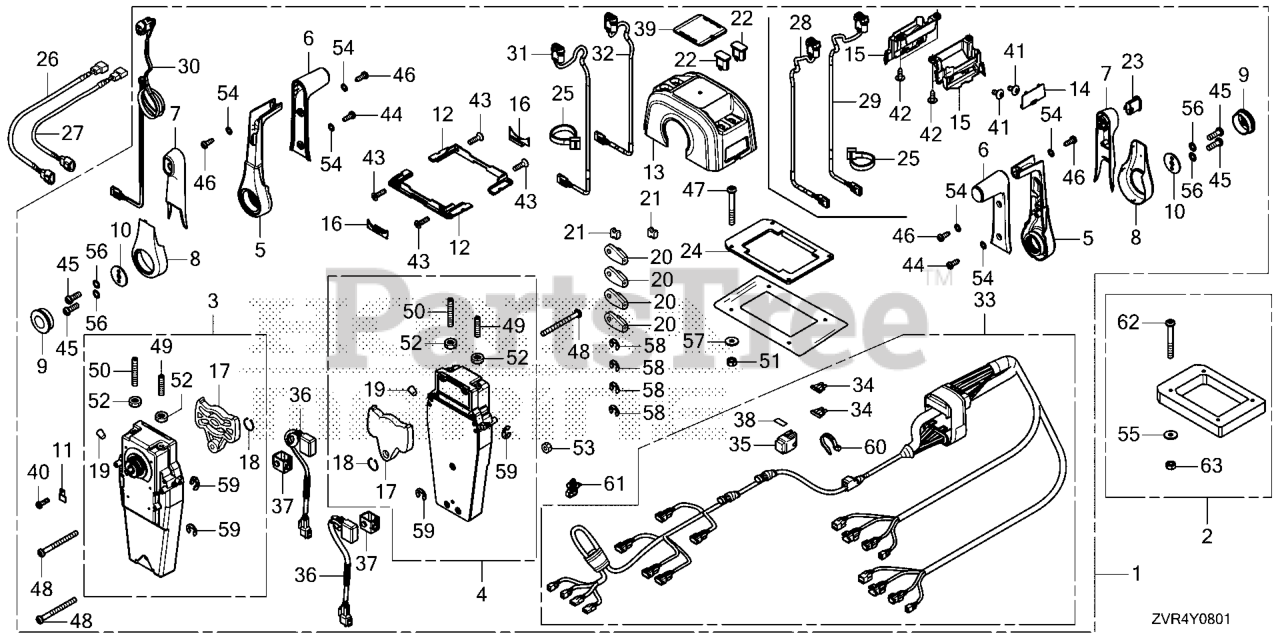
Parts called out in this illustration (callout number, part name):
1	BOX KIT
2	SPACER KIT, REMOTE CONTROL BOX (TOP MOUNT DUAL)
3	HOUSING ASSY., L. (INNER) (TOP MOUNT) (NOT AVAILABLE)
4	HOUSING ASSY., R. (INNER) (TOP MOUNT) (NOT AVAILABLE)
5	HANDLE, REMOTE CONTROL (NOT AVAILABLE)
6	COVER, GRIP
7	GRIP
8	COVER, LEVER (NOT AVAILABLE)
9	BUTTON, THROTTLE (NOT AVAILABLE)
10	PLATE, HANDLE
11	PLATE, CABLE CLAMP
12	BRACKET, REMOTE CONTROL HOUSING (NOT AVAILABLE)
13	HOUSING, DUAL REMOTE CONTROL BOX (NOT AVAILABLE)
14	PLUG, DUAL HOUSING (NOT AVAILABLE)
15	GUIDE, DUAL WATER (NOT AVAILABLE)
16	HOUSING, LEAD (NOT AVAILABLE)
17	PLATE, DWELL
18	RING, SNAP (NOT AVAILABLE)
19	GROMMET (NOT AVAILABLE)
20	TERMINAL, CABLE
21	SPACER, CABLE CLAMP
22	CAP, BLANK (NOT AVAILABLE)
23	CAP, POWER TRIM-TILT BLANK (NOT AVAILABLE)
24	GASKET, DUAL (LOOSE PARTS) (NOT AVAILABLE)
25	BAND, TY-RAP (POWER TRIM-TILT) (NOT AVAILABLE)
26	SUB-HARNESS ASSY., POWER TRIM-TILT (A)
27	SUB-HARNESS ASSY., POWER TRIM-TILT (B)
28	SWITCH ASSY., TROLLING CONTROL (PORT) (NOT AVAILABLE)
29	SWITCH ASSY., TROLLING CONTROL (STAR) (NOT AVAILABLE)
30	SWITCH ASSY., POWER TRIM-TILT (NOT AVAILABLE)
31	SWITCH ASSY., POWER TRIM-TILT (PORT) (NOT AVAILABLE)
32	SWITCH ASSY., POWER TRIM-TILT (STAR) (NOT AVAILABLE)
33	CABLE ASSY.
34	FUSE, BLADE (3A)
35	COVER ASSY., FUSE (3A)
36	RELAY ASSY., CONTROL (NOT AVAILABLE)
37	HOLDER, RELAY (NOT AVAILABLE)
38	LABEL, FUSE (3A)
39	MARK, REMOTE CONTROL (DUAL) (NOT AVAILABLE)
40	SCREW, PAN (5X16)
41	SCREW, TRUSS (5X10) (NOT AVAILABLE)
42	SCREW, TRUSS (5X16) (TAPPING) (NOT AVAILABLE)
43	SCREW, PAN (5X18)
44	SCREW, PAN (5X14) (TAPPING) (NOT AVAILABLE)
45	SCREW, PAN (6X18)
46	SCREW, PAN (5X14) (TAPPING)
47	SCREW, PAN (5X40)
48	SCREW, PAN (5X55)
49	BOLT, STOPPER (F) (NOT AVAILABLE)
50	BOLT, STOPPER (R) (NOT AVAILABLE)
51	NUT, HEX. (5MM)
52	NUT (6MM) (LOOSE PARTS)
53	NUT, HEX. (5MM)
54	WASHER, LOCK (5MM)
55	WASHER, PLAIN (5MM)
56	WASHER, LOCK (6MM)
57	WASHER, PLAIN (5MM)
58	E-RING (6MM) (LOOSE PARTS)
59	E-RING (6MM) (LOOSE PARTS)
60	HOLDER, CONNECTOR (128.6MM) (NATURAL)
61	CLIP, HARNESS BAND (NOT AVAILABLE)
62	SCREW, PAN (5X65)
63	NUT, HEX. (5MM)
